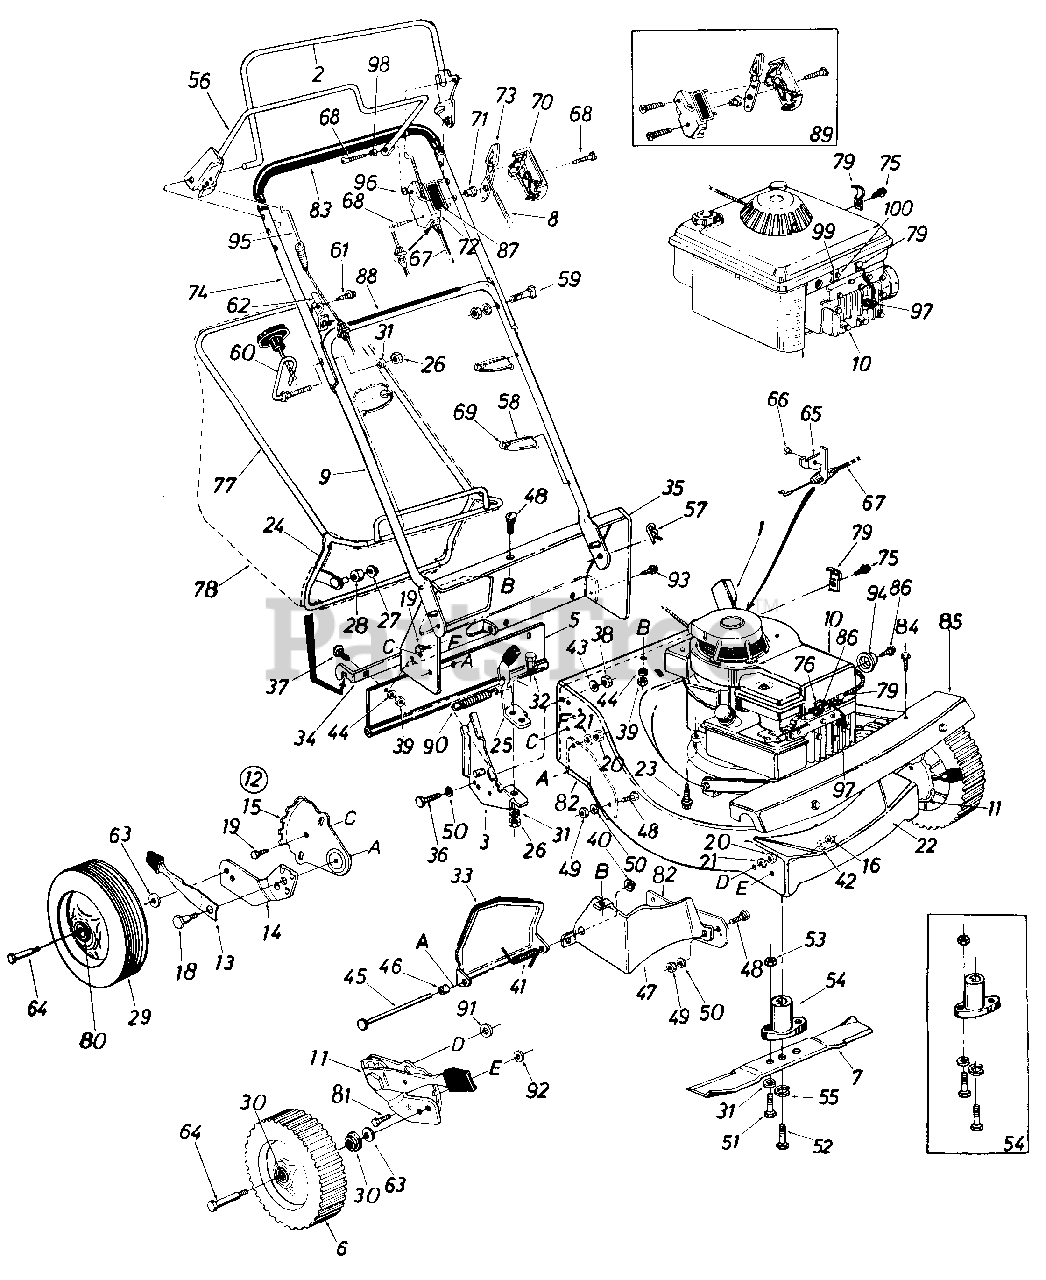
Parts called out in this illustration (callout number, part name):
1	Handle Brkt. Ass'y.-L.H.
2	Control Handle Ass'y.-L.H.
3	Handle Brkt. Ass'y.-R.H.
5	Rear Flap Ass'y.
6	Front Wheel Ass'y. Comp.
7	21" Blade
8	Throttle Wire-58"
9	Lower Handle
10	Engine
11	L.H. Height Adj. Ass'y.
12	R.H. Height Adj. Ass'y.
13	Spring Lever
14	Pivot Bar-L.H.
15	Index Plate
16	Hex Cent. L-Nut 3/8-16 Thc.
18	Shld. Bolt .500" Dia. x .430
19	Hex L-Wash. Hd. AB-Tap Scr. 1/4 x.62" Lg.
20	Hex Nut 3/8-16 Thd.
21	Bell-Wash. .39" I.D. x 1."
22	21" Deck Ass'y.
23	Self-Tap Screw 3/8-16 x 1.0"
26	Hex Nut 5/16-18 Thd.
27	Push Nut 3/8" Rod
28	Plastic Roller
29	Wheel Ass'y. Comp. (Waffle Tread)
30	Bearing
31	L-Wash. 5/16" I.D.
32	Shld. Bolt .437" Dia. x .162
33	Chute Door
34	Grass Catcher Hitch Brkt.
35	Rear Discharge Deck Section
36	Hex Bolt 1/4-28 x .75" Lg.
37	Carr. Bolt 1/4-20 x .75" Lg.
38	Hex Nut 1/4-28 Thd.
39	Sems Nut 1/4-20 Thd.
40	Push Nut 1/4" Rod
41	Torsion Spring
42	L-Wash. 3/8" I.D.
43	Bell-Wash. 1/4" I.D. x .88"
44	Fl-Wash. .285" I.D. x 1.25"
45	Hinge Pin .250" Dia. x 7.25"
46	Spacer.262" I.D. x .31" O.D
47	Rear Baffle
48	Carriage Bolt 1/4-20 x .50"
49	Hex Nut 1/4-20 Thd.
50	L-Wash. 1/4" I.D.
51	Hex Bolt 5/16-24 x 1.00" Lg. (Grade 5)
52	Hex Bolt 3/8-24 x 2.25" Lg. (Grade 5)
53	Hex Nut 5/16-24 Thd.
54	Blade Adapter Kit
55	L-Wash. 3/8" I.D.-H.D.
56	S.P. Bail Ass'y.
57	Intern. Cot. Pin 5/16" Dia.
58	Cable Tie
59	Curved Carriage Bolt 5/16-18 x 1.38" Lg.
60	Rope Guide Bolt
61	Hex AB-Tap Scr. 5/16 x .75"
62	Cable Brkt.
63	Bell-Wash. .40" I.D. x .88"
64	Axle Bolt
65	Cable Bracket
66	Pop Rivet .156" Dia. x .379
67	Brake Control Cable-43"
68	Truss Mach. Hd. "B" Tap Scr. #12 x 1.50" Lg.
69	Cable Anchor
70	Control Panel Half
71	Control Disc Pin
72	Control Panel Hal
73	Throttle Control Lever
74	Upper Handle
75	Hex AB-Tap Scr. #10 x .38"
76	Casing Clamp
77	Grass Catcher Upper Frame
78	Grass Bag
79	Casing Clamp
80	Fortiflex Bearing
81	Hex Bolt 3/8-16 x .75
82	Side Baffle
83	Grip
84	Hex Wash. Hd. Self-Tap Scr. 1/4-20 x .50" Lg.
85	Drive Cover
86	Hex Wash. Hd. AB-Tap Scr. #8 x .38" Lg.
87	Instruction Label
88	Control Label
89	Kit-Control Hsg. Comp.
90	Extension Spring
91	Fl-Wash. .406 I.D. x 1.245
92	Fl-Wash. .39 I.D. x .993
93	Hex Tap Scr. 5/16 x .50"
94	Exhaust Deflector
95	Drive Clutch Cable w/Spr.
96	Spr-Wash. .206 I.D. x .448
97	Spark Plug Insulator
98	Spacer .23 I.D. x .30 O.D.
99	Casing Clamp
100	Hex AB-Tap Scr. #10 x .62"
